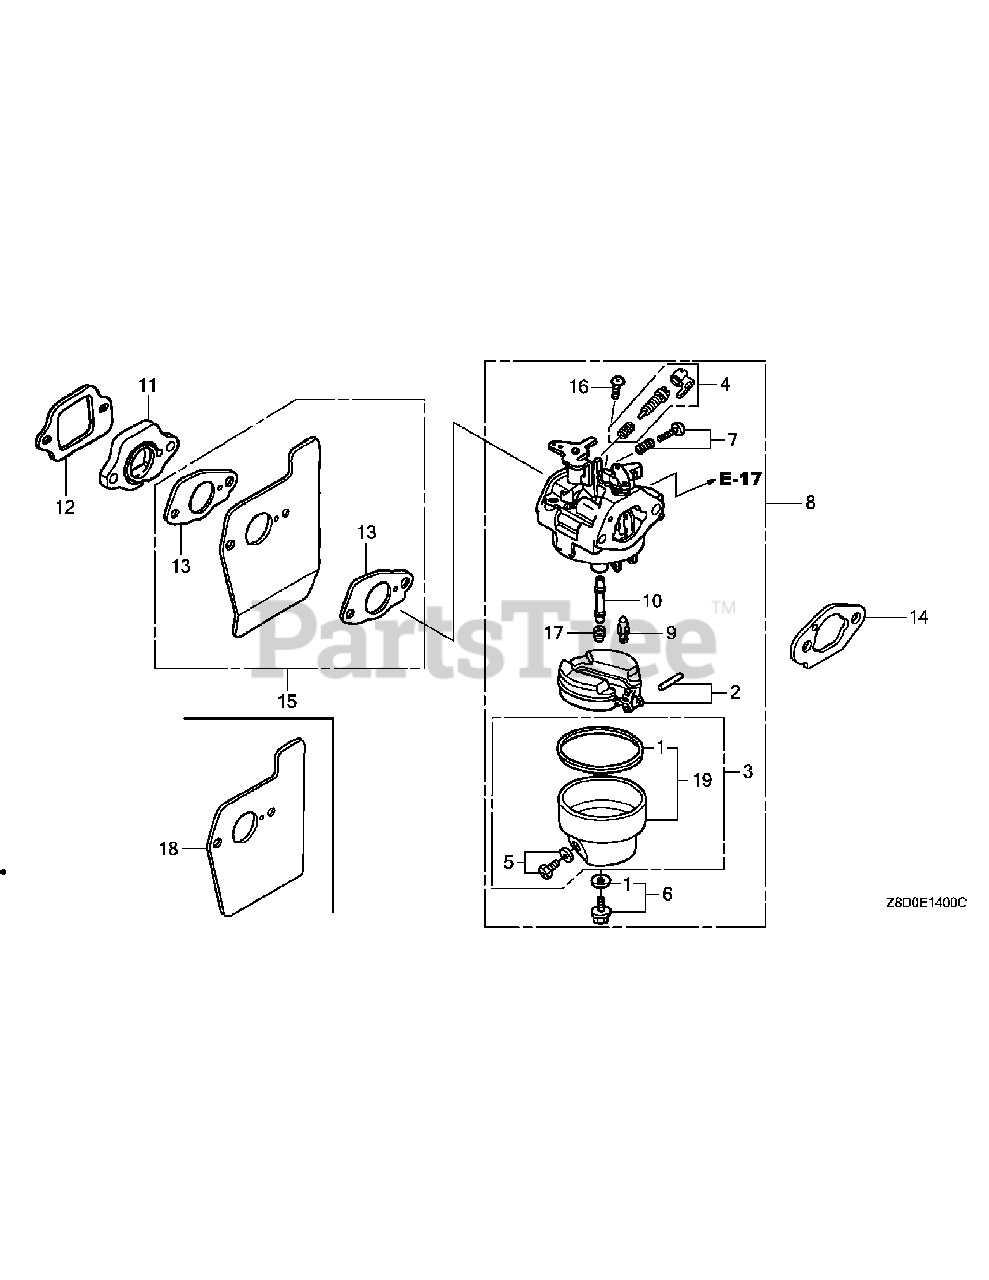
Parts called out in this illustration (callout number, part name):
1	Packing Set
3	Float Chamber Set
5	Drain Screw Set
6	Screw Set B
7	Screw Set (Throttle Stop)
8	Carburetor Assembly (BB65C A)
9	Float Valve
10	Main Nozzle
11	Carburetor Insulator
12	Insulator Packing
13	Carburetor Packing
14	Carburetor Packing
16	Pan Screw, 5 x 6
17	Main Jet, #65
17	Main Jet, #68
17	Main Jet, #70
19	Float Chamber Set
